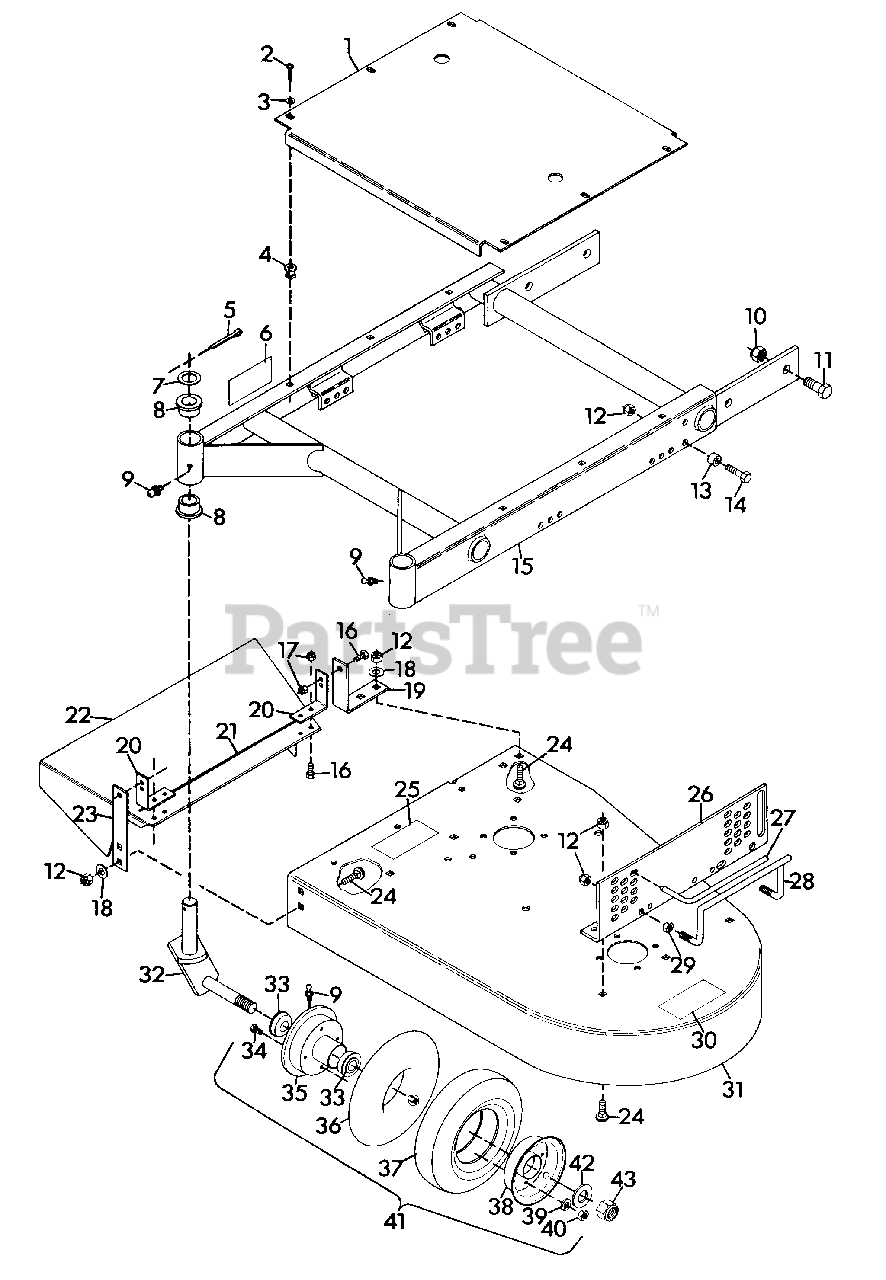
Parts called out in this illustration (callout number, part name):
1	COVER, BELT
2	SCREW, TAPPING 1/4-20X.625 P/HD
3	WASHER, FLAT .281X.625X.065
4	GROMMET, PLASTIC
5	PIN, COTTER .187X1.50
6	DECAL, DANGER HAND
7	RACE, BEARING THRUST
8	BUSHING, PIVOT
9	FITTING, LUBE 1/4-28
10	NUT, LOCK 5/8-11
11	BOLT, HEX 5/8-11X1.50
12	NUT, LOCK 3/8-16
13	BUSHING .391X.622X.670
14	BOLT, HEX 3/8-16X1.50
15	WELDMENT, FRAME
16	BOLT, HEX 5/16-18X.75
17	NUT, LOCK 5/16-18
18	WASHER, FLAT .406X.812X.065
19	BRACKET
20	BRACKET
21	STRIPE
22	CHUTE, DISCHARGE
23	BRACKET
24	BOLT, 3/8-16X1.00 RD HD SQ NK
25	DECAL, WARNING EYE
26	BRACKET, MOWER SIDE SUPPORT L.H.
27	PIN, MOWER LOCKING
28	HANDLE
29	NUT, HEX 3/8-16
30	DECAL, DANGER FOOT
31	WELDMENT, 32" PRO DECK
32	WELDMENT, CASTER FORK
33	BEARING, GAUGE WHEEL
34	BOLT, HEX 3/8-24X.75
35	WHEEL, HALF
36	TUBE, INNER
37	TIRE, GAUGE WHEEL
38	WHEEL, HALF PLAIN
39	WASHER, LOCK 3/8 SP HEAVY
40	NUT, HEX 3/8-24
41	WHEEL, GAUGE
42	WASHER, FLAT .812X1.496X.134
43	NUT, LOCK 3/4-10
NS	BRACKET, MOWER SIDE SUPPORT R.H.
NS	DECAL, PRO-32
